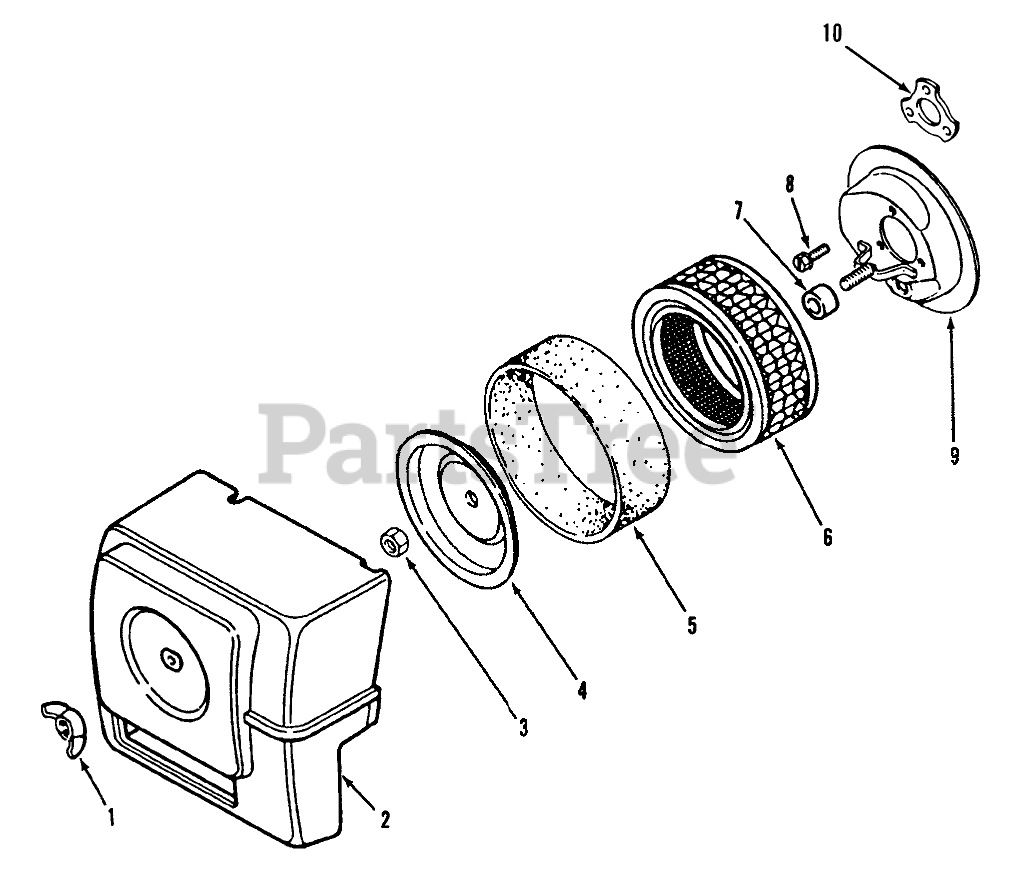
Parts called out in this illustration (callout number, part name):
1	Wing Nut 1/4-20
2	Air Cleaner Cover
3	Jam Nut
4	Cover-Element
5	Precleaner
6	Element
7	Seal
8	Screw
9	Base-Air Cleaner
10	Air Horn Gasket
